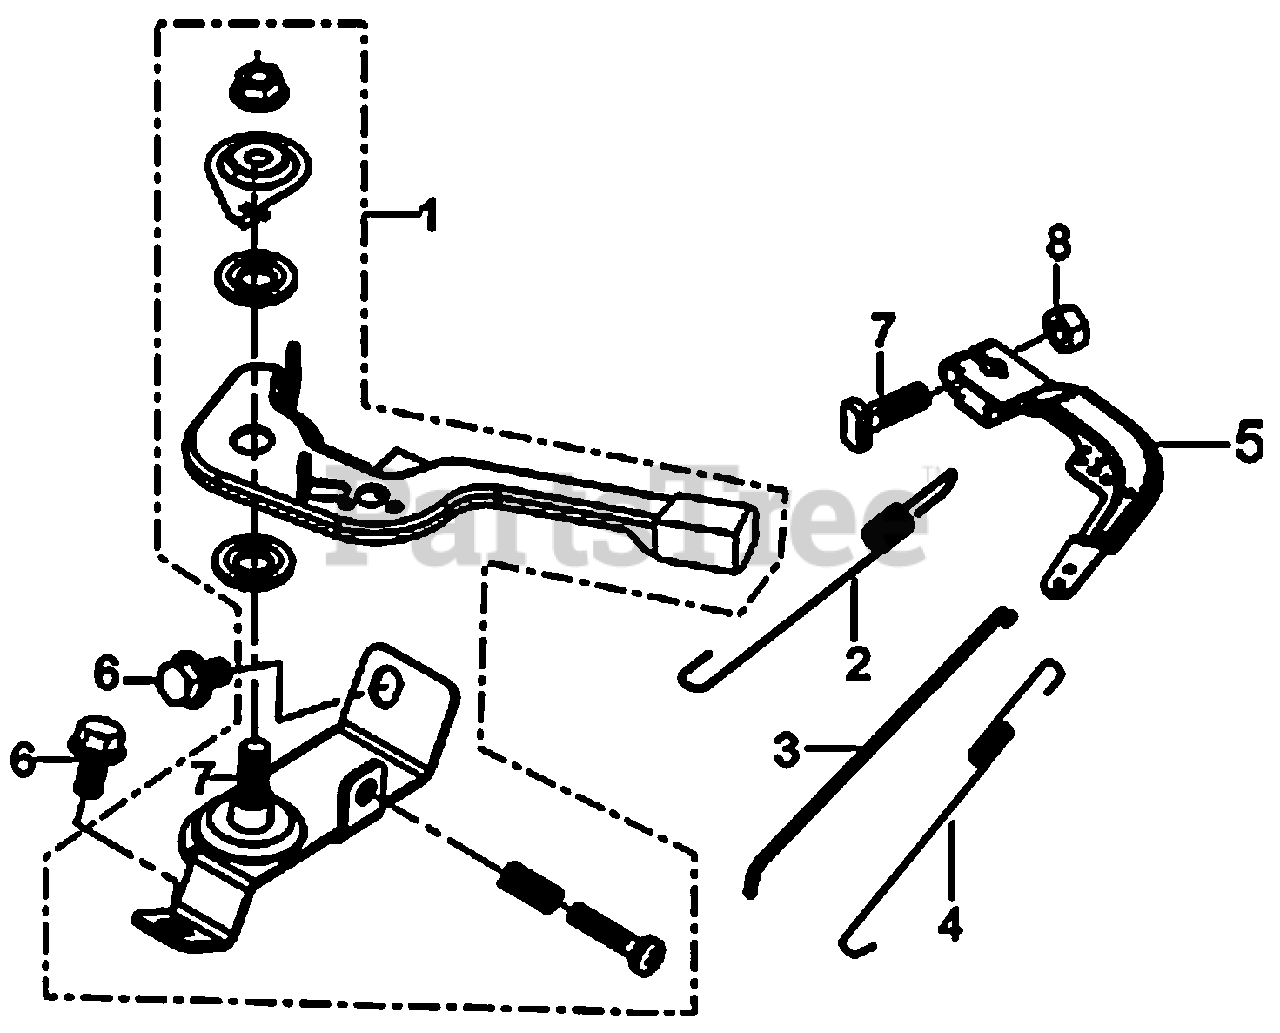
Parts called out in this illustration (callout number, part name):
1	CONTROL ASSY, THROTTLE
2	SPRING, GOVERNOR
3	ROD, GOVERNEOR
4	SPRING, THROTTLE VALVE RETURNING
5	SUPPORT SUBASSEMBLY, GOVERNOR
7	BOLT, GOVERNOR SUPPORT
